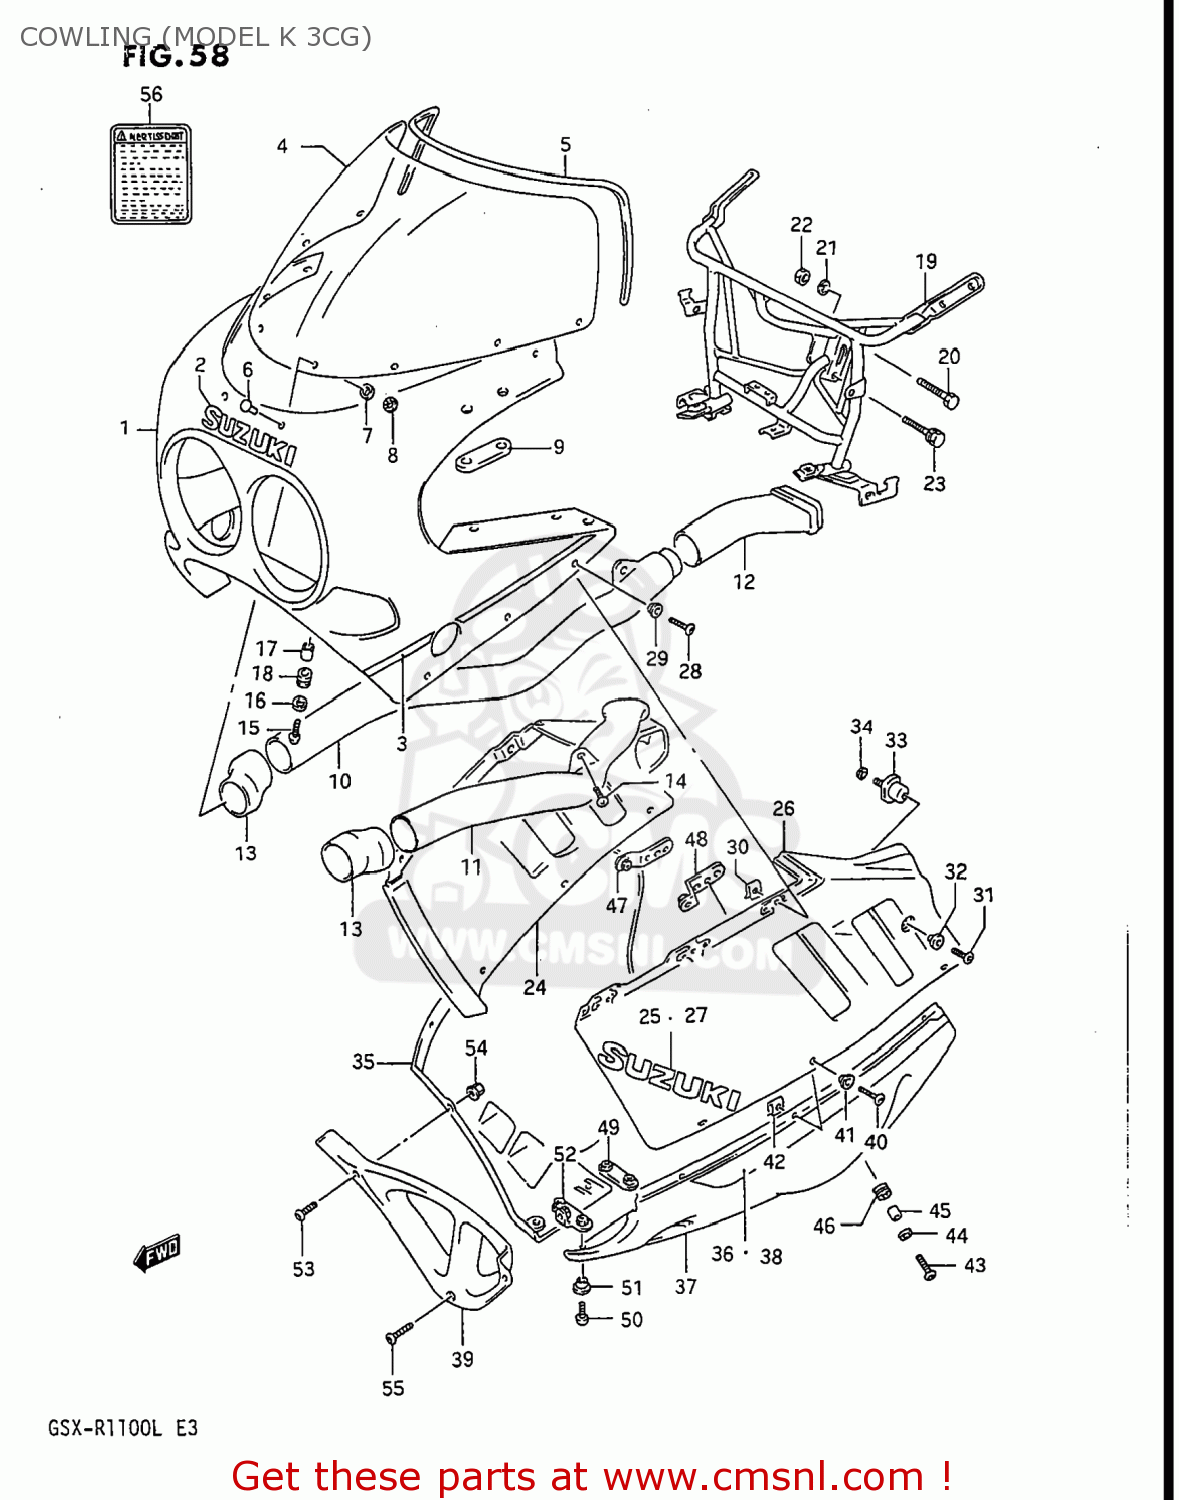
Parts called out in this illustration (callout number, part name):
1	BODY ASSY,COWLING
2	EMBLEM,COWLING FR
3	TAPE SET,COWLING
4	SCREEN SET,WINDOW
5	MOLDING
6	PIN,WINDSCREEN
7	CUSHION
8	NUT
9	CUSHION,RR VIEW MIRRORR
10	PIPE,AIR INTAKE FR,R
11	PIPE,AIR INTAKE,FRONT
12	PIPE,AIR INTAKE RR,R
13	JOINT,AIR INTAKE
14	SCREW, CENTER
15	SCREW(6X20)
16	WASHER(6.5X18X1)
17	SPACER
18	CUSHION
19	BRACE,COWLING
20	BOLT
21	WASHER,LOCK,8.
22	NUT ,8MM
23	BOLT
24	COVER,COWLING SIDE,R
25	EMBLEM,COWLING SIDE
26	COVER,COWLING SIDE,L
27	EMBLEM,COWLING SIDE
28	SCREW(5X18)
29	WASHER(5.2X14X1.5)
30	NUT,HEADLAMP HOUSING,UPPER
31	SCREW(6X12)
32	WASHER(6.3X16X1.5)
33	CUSHION,COWLING
34	WASHER,LOCK
35	COWLING COMP,UNDER,RIGHT
36	TAPE,COWLING,UNDER,RIGHT
37	COWLING COMP,UNDER,LEFT
38	TAPE,COWLING,UNDER,LEFT
39	COWLING,UNDER,CENTER
40	SCREW(5X18)
41	WASHER(5.2X14X1.5)
42	NUT,HEADLAMP HOUSING,UPPER
43	SCREW(6X20)
44	WASHER(6.5X18X1)
45	SPACER
46	CUSHION
47	BRACKET
48	BRACE,COWLING UNDER,LH
49	BRACE,COWLING LWR COVER RR
50	SCREW(6X16)
51	WASHER(6.3X16X1.5)
52	BRACE,COWLING LWR COVER
53	SCREW(5X14)
54	NUT
55	SCREW(6X16)
56	LABEL (WARNING)
